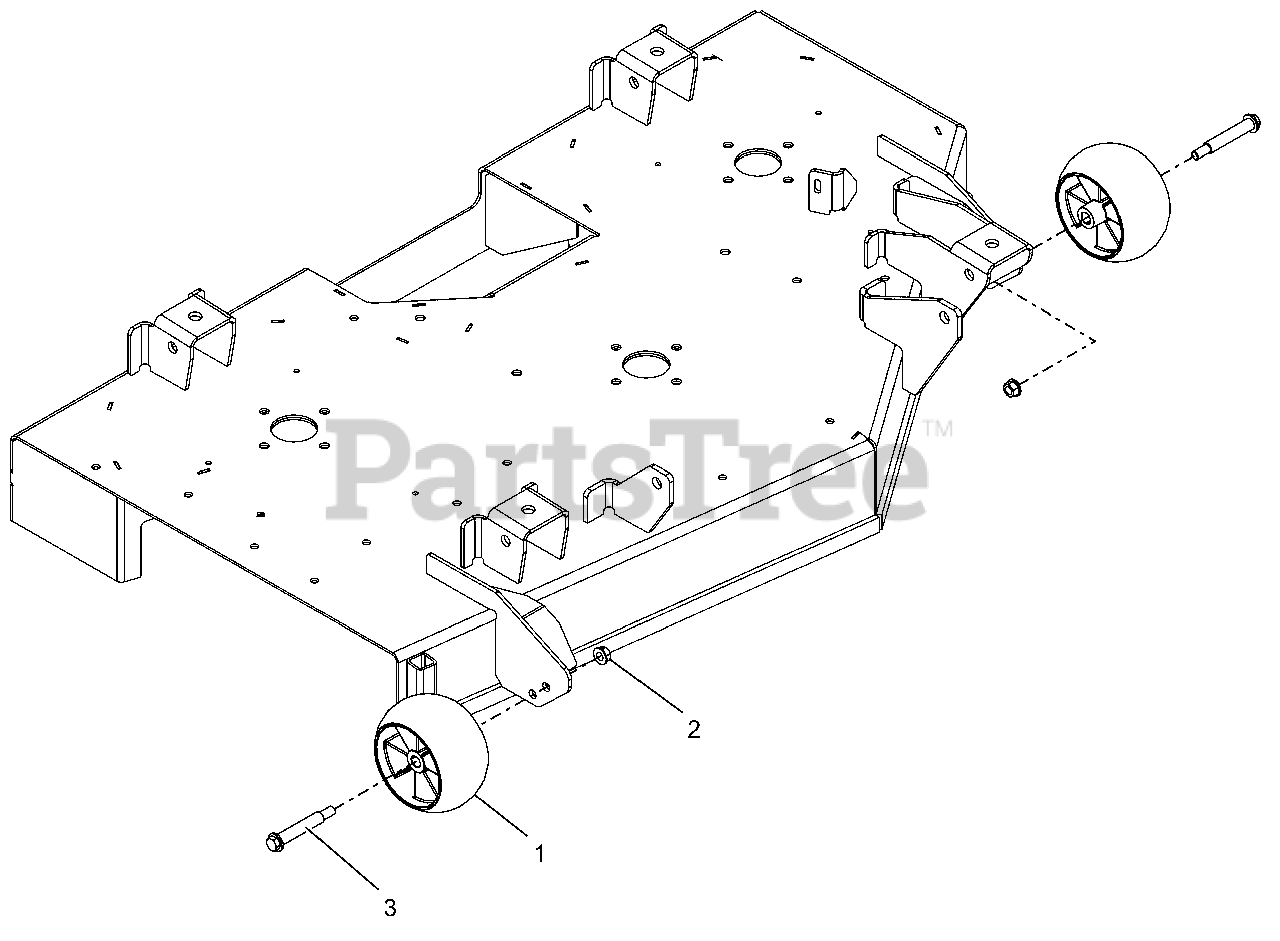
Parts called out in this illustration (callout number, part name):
1	ANTI-SCALP WHEEL - 5X OS
2	NUT-LK-CTR-FLG .375-16 GF ZCC
3	BLT-SHLDR .38-16X2.50 HWH G5
